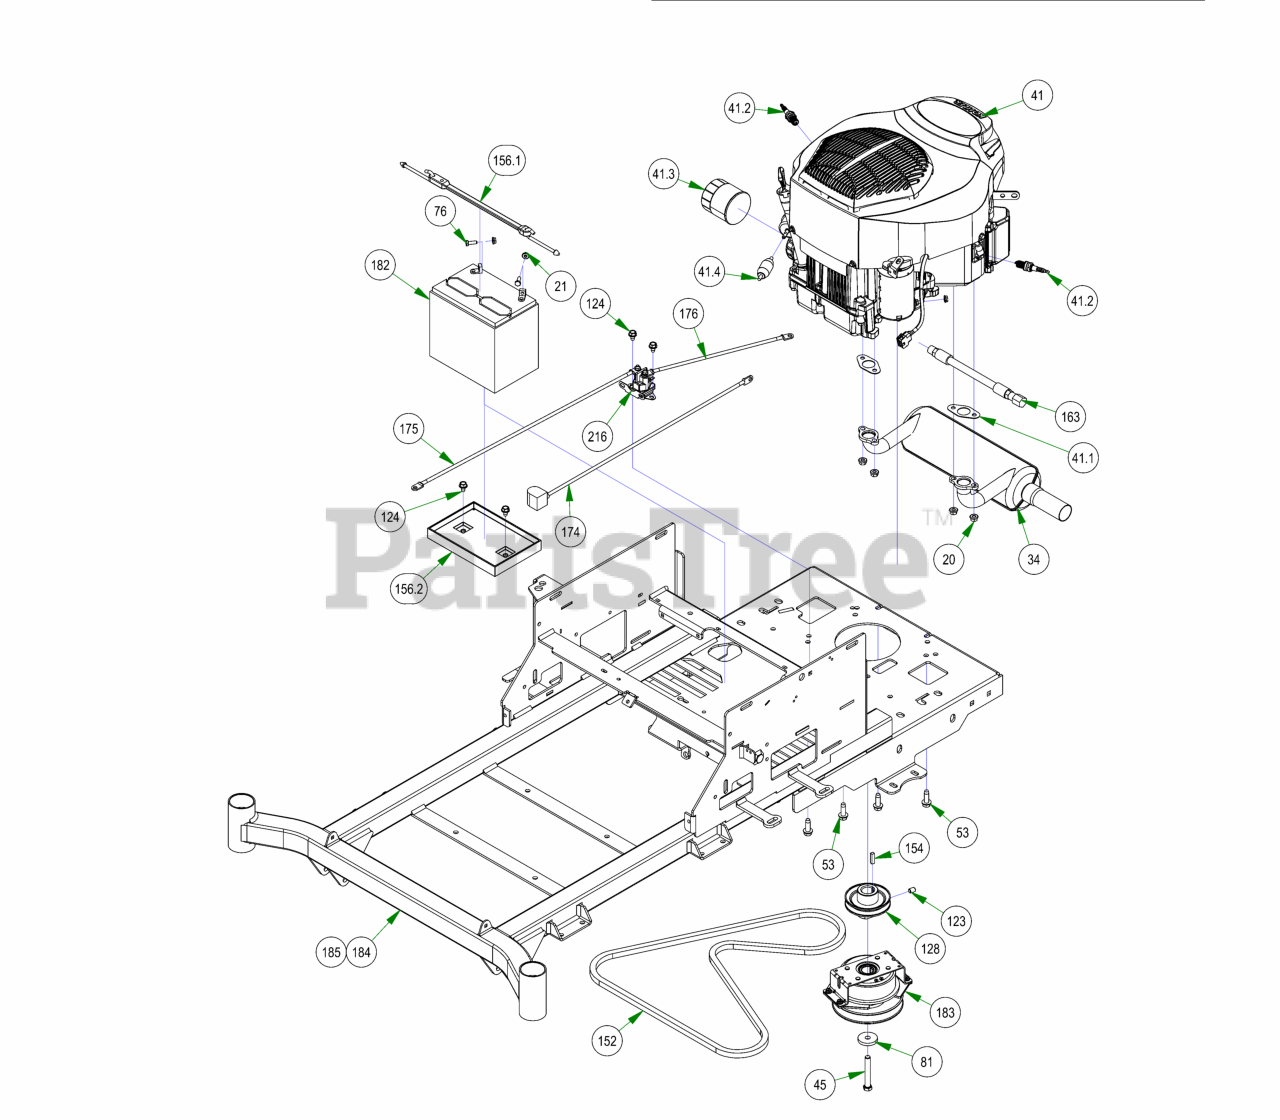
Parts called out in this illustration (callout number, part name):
20	M8 Nut Connects the 015-1012-00 and the 015-8240-00
21	1/4-20 HEX SERRATED FLANGE NUT HARD/ZINC
34	Kohler Muffler
41	25hp Kohler 2014 MZ-KT740-3048
41.1	Exhaust Gasket
41.2	Spark Plug
41.3	25 HP Kohler Oil Filter ZT?MZ
41.4	Universal Inline Fuel Filter
45	7/16-20x3” Hex Bolt GR 8 W/ Patch
53	3/8-16 X 1-1/8 HEX WASHER UNSLOT SERRATED (TRI-LOB) TRS ZINC YELLOW
76	1/4-20 X 3/4 HEX CAP SCREW (GR.5) ZINC
81	CLUTCH WASHER
123	3/8-16 X 1/2 SOCKET SET SCREW (CUP PT) PLAIN
124	5/16-18 X 1/2 HWH unslot (F) tcs zinc
128	3-3/4" Motor Pulley
154	1/4 X 1 SQ MACHINERY KEY 1018 STL PLN
156	2023 Battery Hold Down Assembly Strap
156.1	2023 Rubber Battery Hold Down Strap
156.2	Battery Tray
163	Oil drain Hose
174	24 inch Black Cable – MZ/ZT
175	24" Red Battery Cable
176	12 in red battery cable
182	SP-35 Battery
184	2023 MZ 42-48 Frame - Painted
185	2023 MZ-Avenger 54-60 Frame - Painted
